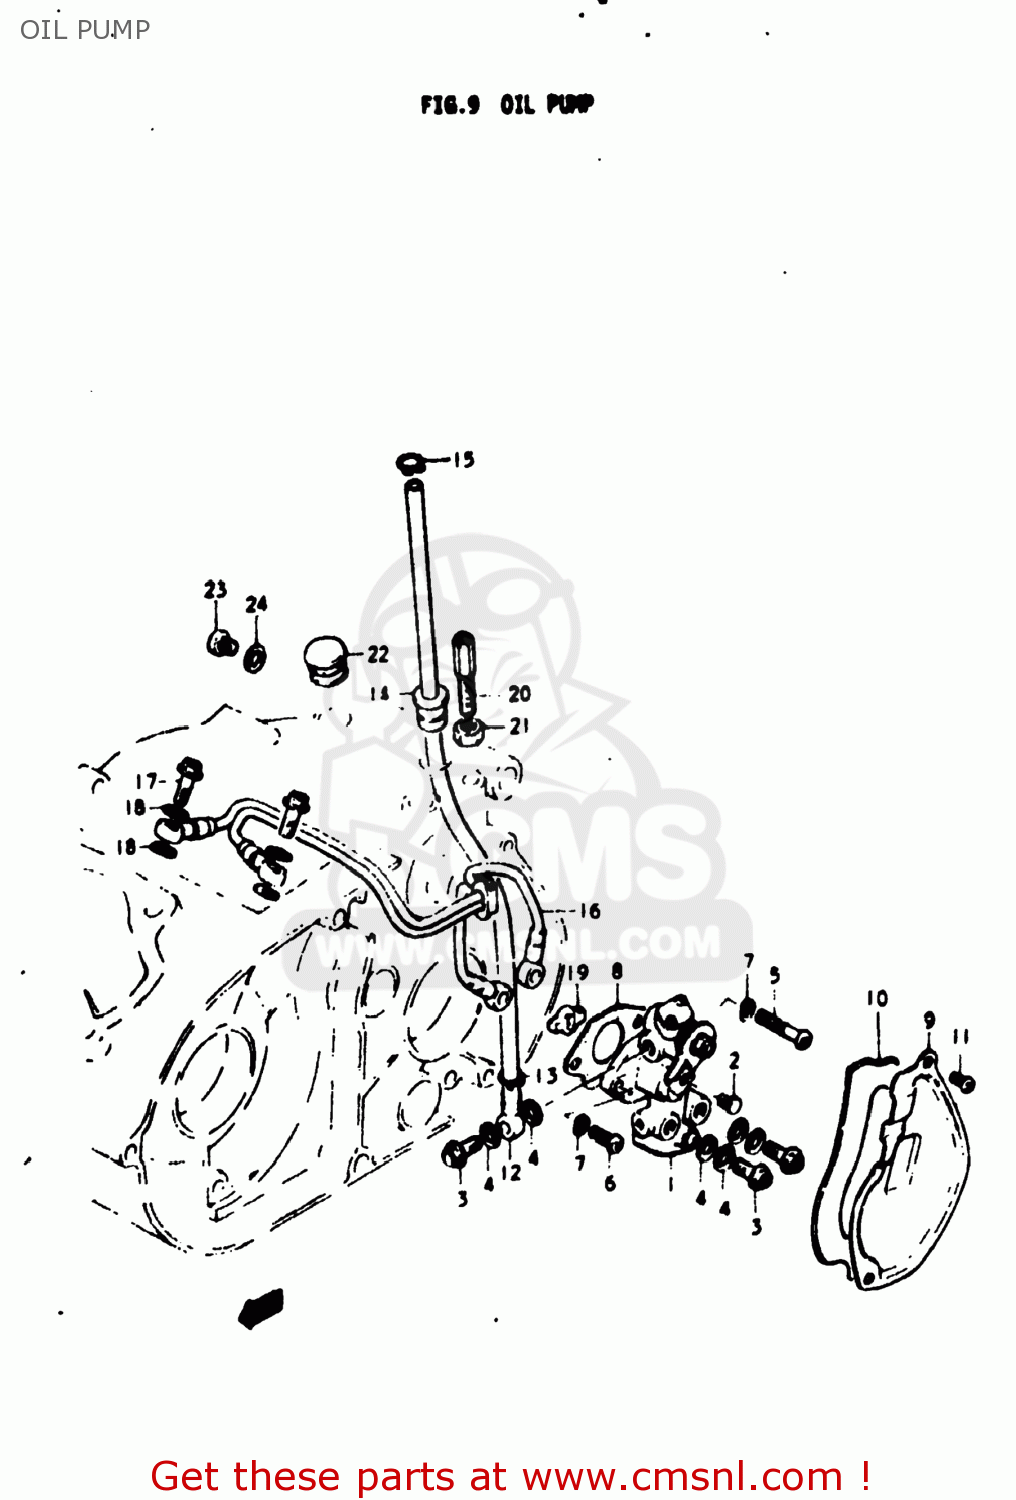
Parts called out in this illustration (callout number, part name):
1	PUMP ASSEMBLY,OIL
2	TERMINAL,CABLE
3	UNION BOLT
4	GASKET (NAS)
5	SCREW
6	SCREW
7	LOCK WASHER
8	GASKET,OIL PUMP (MCA)
9	CAP,OIL PUMP INSPECTION
10	GASKET,OIL PUMP INSPECTION (NAS)
11	SCREW
12	HOSE,OIL NO.1
13	CLIP
14	BUSHING
15	CLIP
16	HOSE,OIL NO.2
17	UNION BOLT
18	GASKET (NAS)
19	PIECE,OIL PUMP DRIVE
20	BOLT
21	NUT
22	Plug
23	SCREW,6X6
24	WASHER
